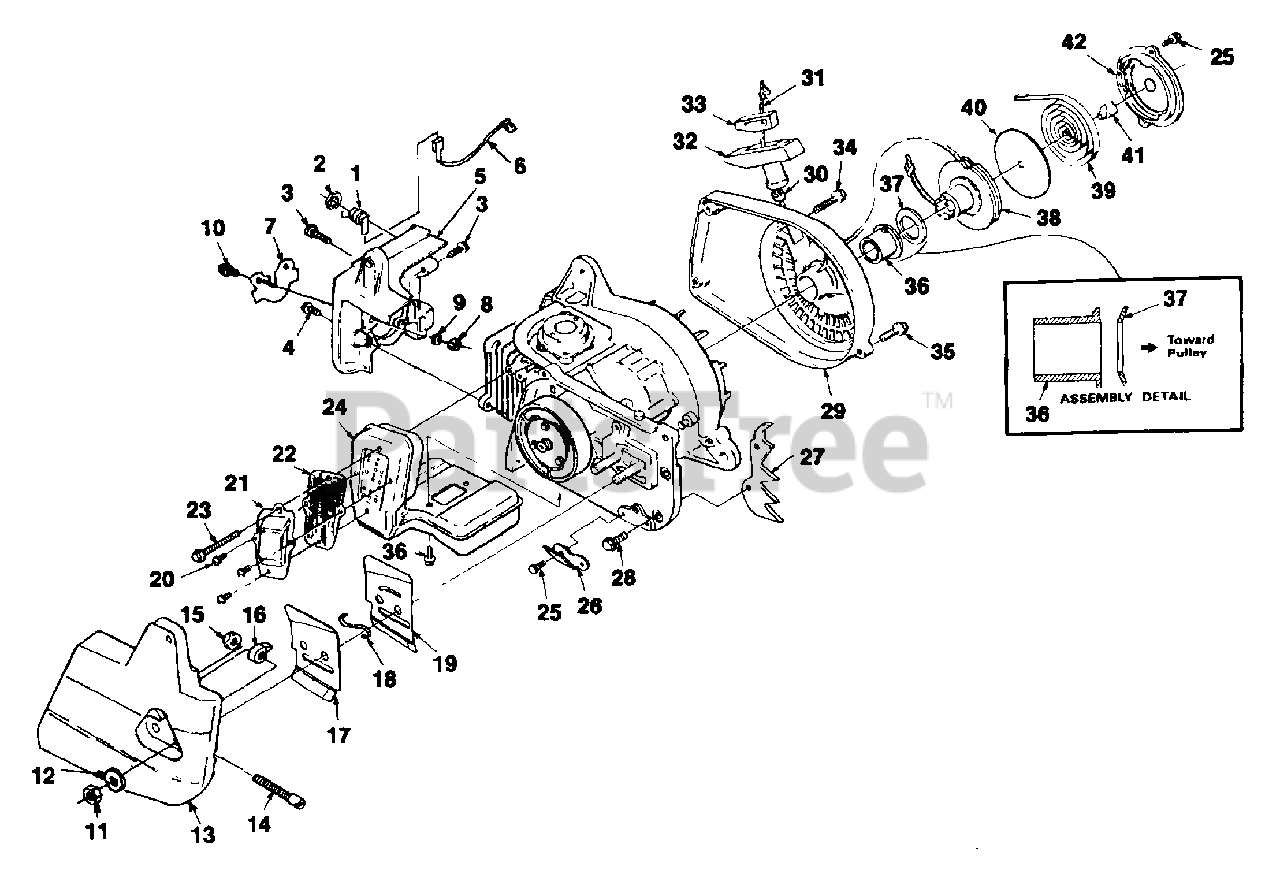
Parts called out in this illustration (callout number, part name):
1	SWITCH-Grounding
3	SCREW-Hex sems (10-24 x 3/4")
4	SCREW-(10-24 x 1 1/4")
5	SHIELD-Cylinder
6	LEAD-Ground
7	SHIELD-Insert
8	NUT-Centerlock (8-32)
9	WASHER-Flat (#8)
10	SCREW-Hex sems (8-32 x 3/8")
11	NUT-Hex (5/16-18)
12	WASHER-Flat (5/16")
13	COVER-Drivecase
14	SCREW-Guide bar adjusting
15	NUT-Centerlock (10-32)
16	PIN-Guide bar adjusting
17	PLATE-Guide bar (Outer)
18	SPRING-Guide bar
19	PLATE-Guide bar (Inner)
21	PLATE-Exhaust
22	SPARK ARRESTOR SCREEN
26	STOP-Chain
27	BUMPER-Spiked (accessory)
28	SCREW-Hex hd. (10-24 x 3/8")
29	HOUSING-Rewind starter
30	BUSHING-Rope
31	ROPE-Starter (38" #4)
32	GRIP-Starter rope
33	INSERT-Rope retaining
34	SCREW-Hex sems (10-24 x 1 3/8")
35	SCREW-w/Washer (10-24 x 1 1/8")
36	BUSHING-Starter
37	WASHER-Spring
38	PULLEY & CUP
39	Spring-Rewind
40	SPRING-Shield
41	LOCK-Spring
42	STARTER COVER & DECAL KIT
